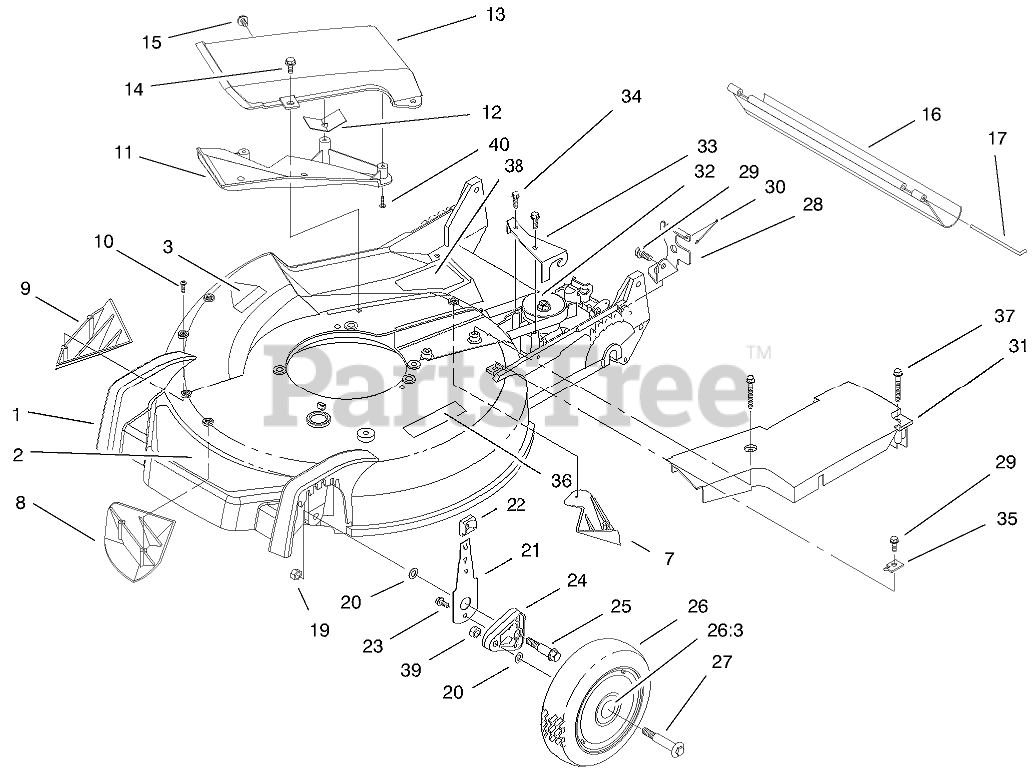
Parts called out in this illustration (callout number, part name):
1	HOUSING
2	DECAL - DECK
3	DECAL-DANGER
7	KICKER-REAR
8	KICKER-FRONT
9	KICKER-RH
10	SCREW-PPH
11	Deflector-Recycler
12	Guard-Cover
13	COVER W/DEFLECTOR
14	SCREW-HWH
15	SCREW AND WASHER ASM
16	SHIELD-TRAILING
17	ROD-SHIELD
19	NUT-LOCK
20	WASHER
21	FRONT SPRING ARM ASM
22	KNOB-ARM
23	SCREW-HWH
24	ARM-PIVOT, FRONT
25	BOLT-SHOULDER
26	WHEEL ASM
26:3	BUSHING
27	BOLT-SHOULDER
28	Bracket-Adj. Trac
29	SCREW-HWHTF
30	RETAINER-CABLE
31	COVER-BELT
32	GEARCASE ASM
33	Bracket-Guide
34	SCREW-HWHTF
35	CLAMP-CABLE
36	DECAL-WARNING
37	SCREW-HHFTF
38	DECAL - DANGER
40	Screw-PPH
